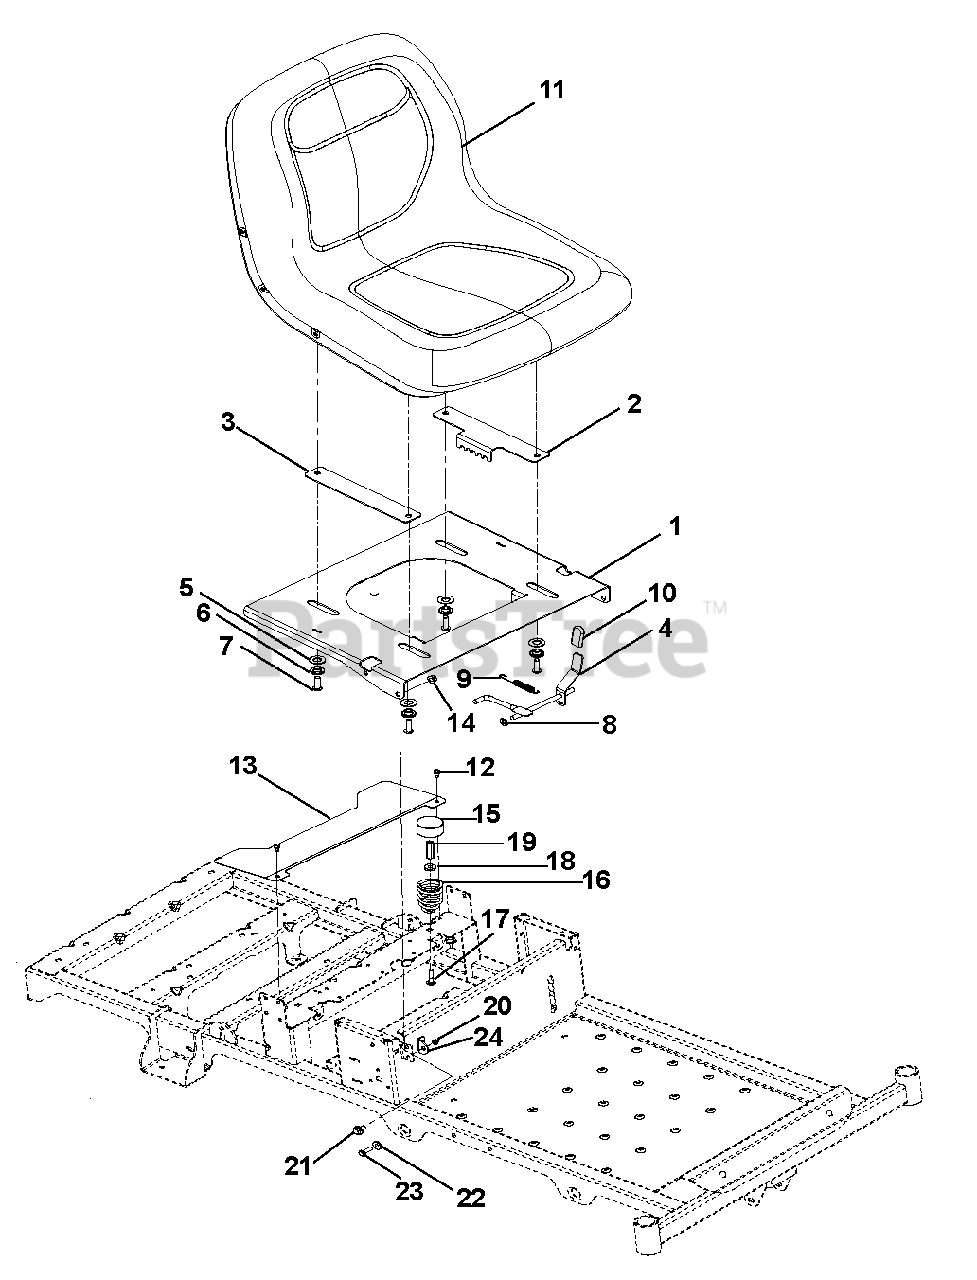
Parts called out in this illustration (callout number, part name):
1	Plate, Adjustable Seat
2	Plate, Adjustable Seat Track
3	Plate Adjustable Seat Slide
4	Weldment, Adjustable Seat Latch
5	Washer, Flat Steel .505 x 1.00 x .062
6	Bushing, Flange .32 x .500 x .344 x .880
7	Screw, Socket Head, Button Head .31-18 x 1.00
8	Push Nut 5/16
9	Weldment, Spring Tension .043 x .44 x 3.31, 5.8
10	Grip, Seat Lever, Grey
11	Seat, Milsco XB180 Grey
12	Screw, Tapping .25-20 x .50 Hex Washer Head Thread
13	Guard, Fan
14	Nut, .38-16 Locking Top Flange
16	Spring, Seat
17	Bolt, Round Head Square Neck .31-18 x 1.50
18	Washer, Flat Steel .328 x .87 x .179
19	Nut, Coupling 5/16-18 x 1.75
20	Nut, 5/16-18 Flange Nyloc
21	Bolt, Shoulder .375-16 x .135
22	Bushing, Flange .325 x .499 x .26 x .88
23	Bolt, Hex .31-18 x 1.00
24	Bracket, Seat Stop
